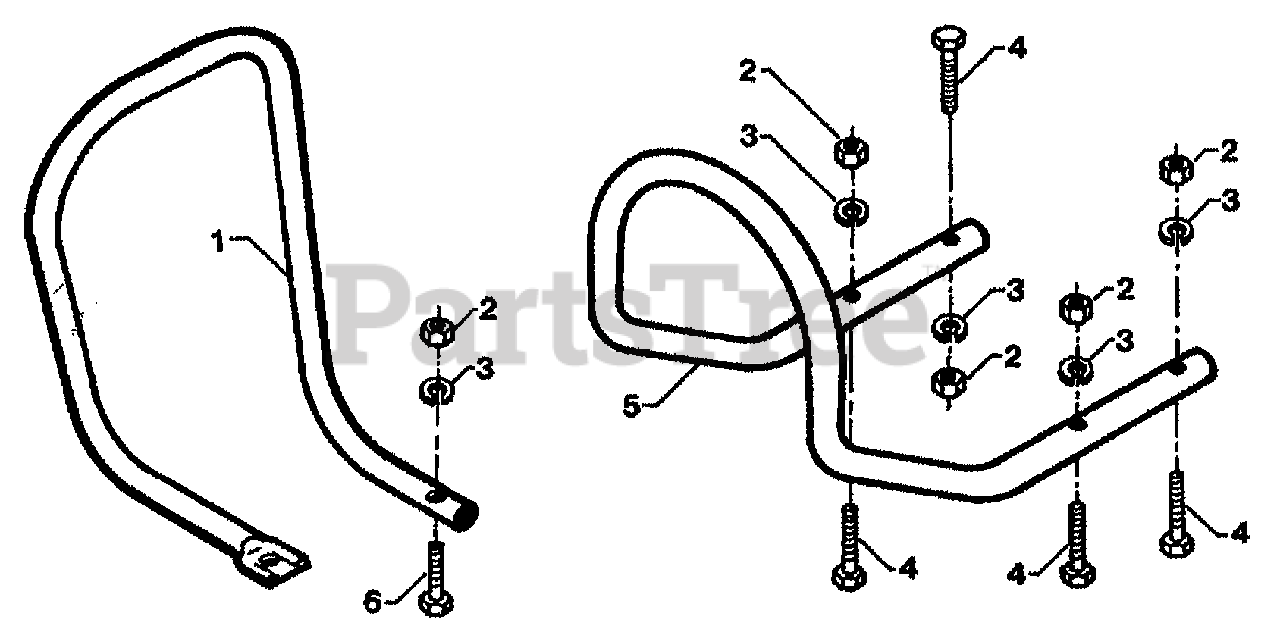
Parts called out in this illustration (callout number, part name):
1	GUARD-CARBURETOR
2	BUMPER-JR/TUFFY
3	SCR-HH 5/16-18X2.5
4	SCR-HH 5/16-18X1.5 G5 ZP
5	WASHER-LK .312 ZP
6	NUT-HEX 5/16-18 ZP
